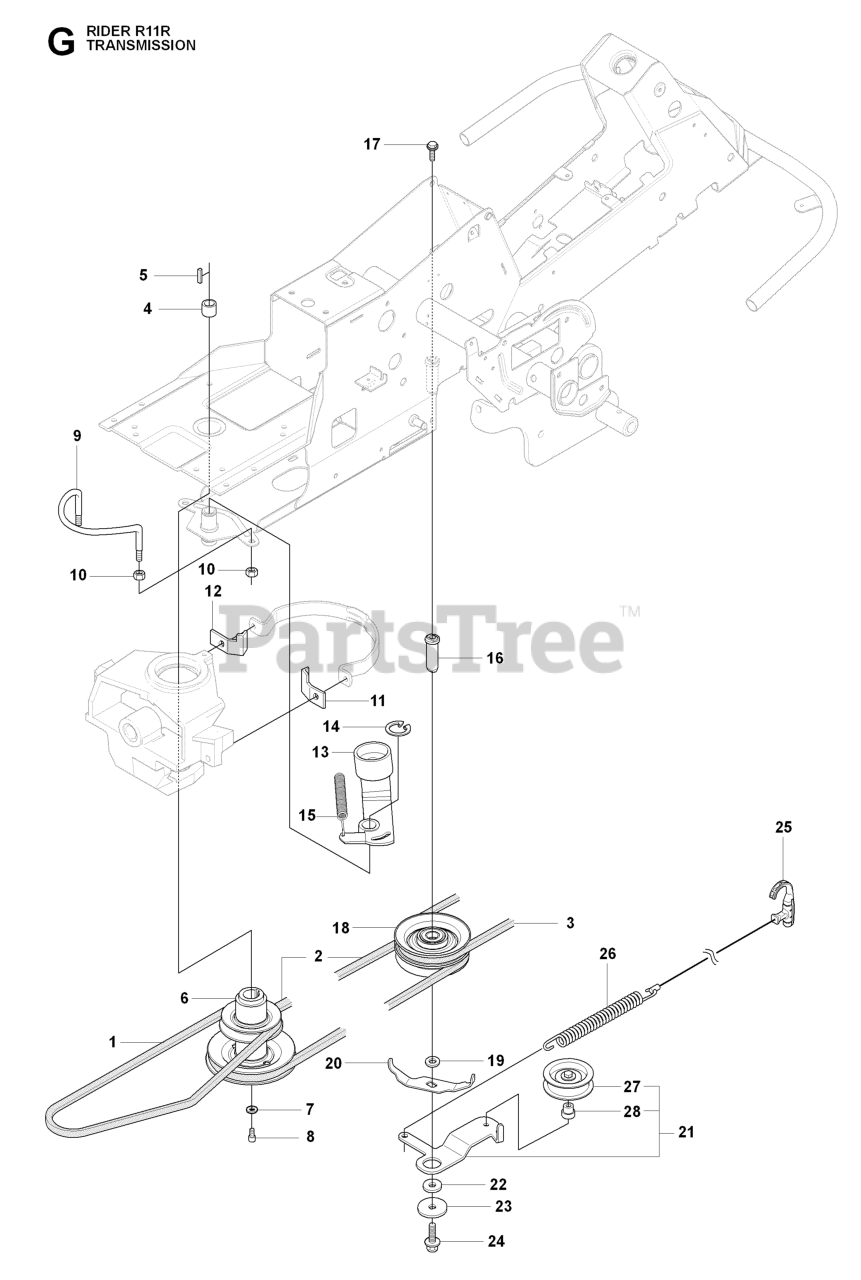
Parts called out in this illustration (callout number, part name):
6	Pulley Cpl
9	BELT GUIDE
10	NUT
11	Belt Guide Cpl., Right
12	Belt Guide Cpl.,Left
14	RETAINING RING SGA 25
16	SHAFT
20	BELT GUIDE
21	BELT TENSIONER ASSY
24	BOLT
27	PULLEY
